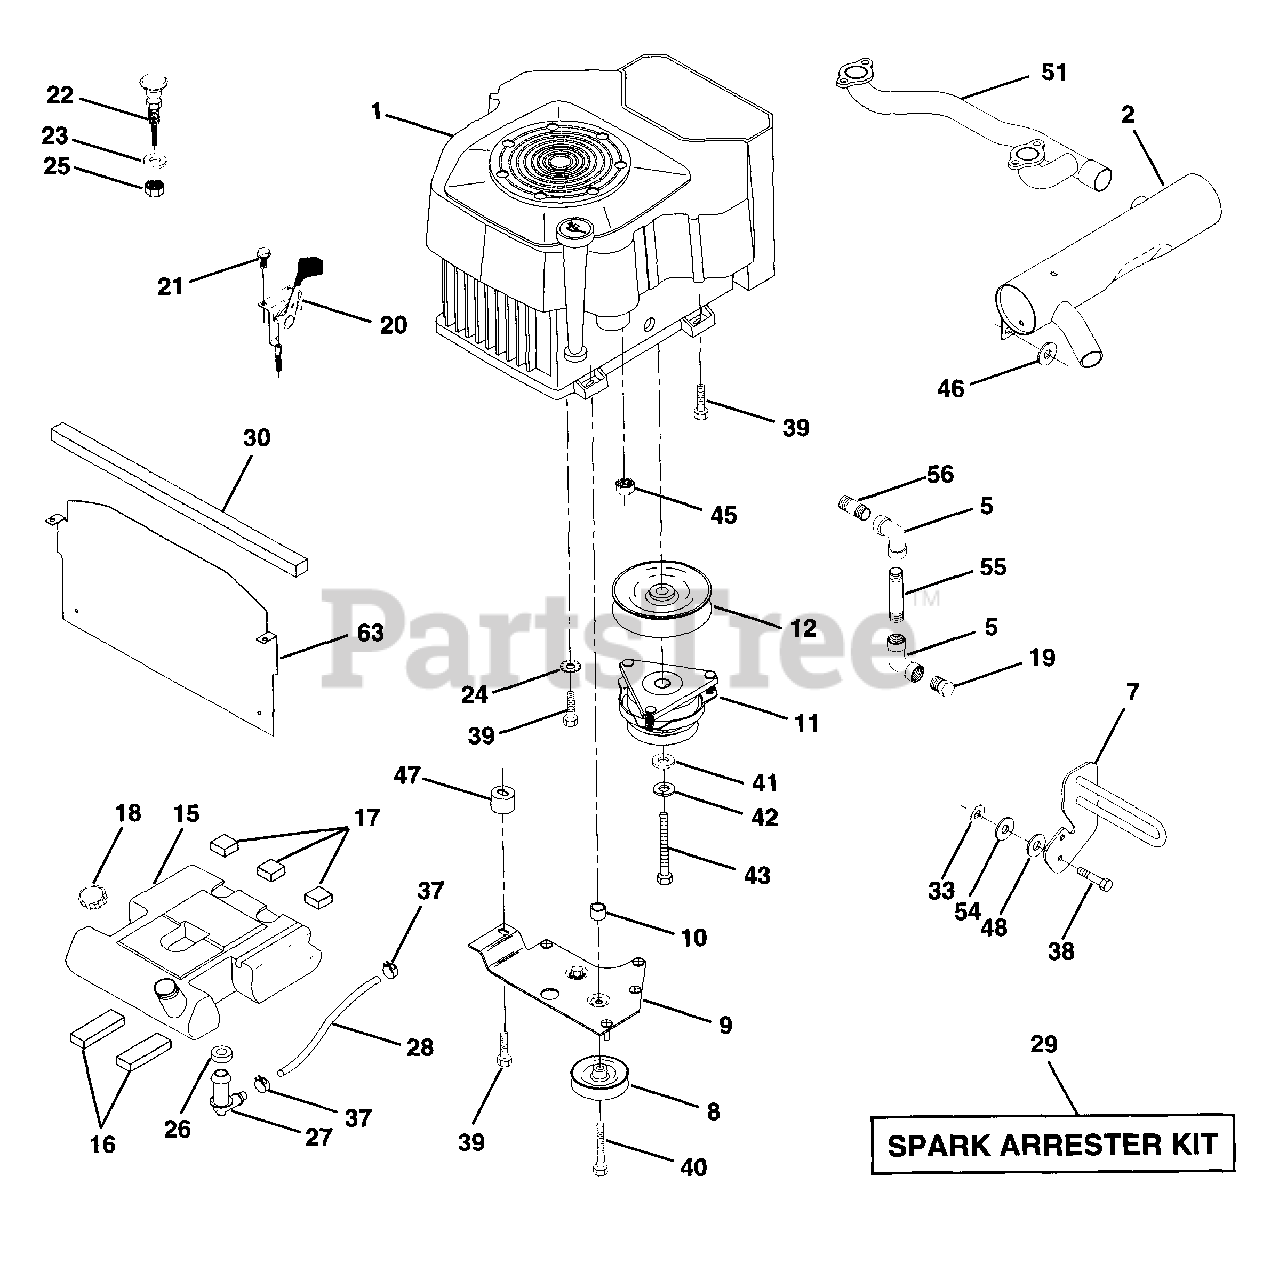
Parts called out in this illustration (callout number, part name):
2	Muffler VGT Cylinder
5	Elbow STD 90 Degree 3/8-18 NPT
7	Muffler Assembly Guard
8	Pulley V-Idler
9	Keeper Asm Belt Engine VGT 96
11	Clutch Electric
12	Pulley Engine VGT Elect Clutch
15	Tank Fuel Rear
16	Pad Spacer
17	Pad Spacer
18	Cap Asm Fuel W/Sym Vented
19	Plug Oil Drain (Order From Engine Manufacturer)
20	Control Throttle
21	Screw Hex Thd Cut 1/4-20 X 5/8
22	Control Choke
23	Washer 13/32 X 13/16 x 16 Ga
24	Washer Ext Tooth 3/8
25	Nut Keps 3/8 - 24 UNF
26	Bushing
27	Stem Tank Fuel
28	Fuel Line
29	Spark Arrester Kit
30	Strip Foam 18"
33	Nut, Hex W/Ins. 3/8-16 UNC
37	Clamp Hose
38	Bolt, Fin Hex 3/8-16 UNC x 1-1/2
39	Screw TT 3/8-16 x 2-1/4 UNC
40	Screw TT 3/8-16 x 4 UNC
41	Washer 1-1/2 OD X 15/32 ID X .250
42	Washer Lock 7/16
43	Bolt Hex 7/16-20 X 4-1/4 Ga 5
45	Nut Flange 1/4-20 Starter Nut
46	Washer 13/32 x 1 x 16 Ga.
47	Spacer Engine
48	Washer 13/32 x 1-1/4 x 7 Ga.
51	Pipe Crossover
54	Washer Flat 13/32 x 7/8 x 14 Ga.
55	Nipple, Pipe 3/8 NPT x 4-1/2
56	Nipple, Pipe 3/8 NPT x 1.00
63	Shield, Heat VGT YP/Husq.
